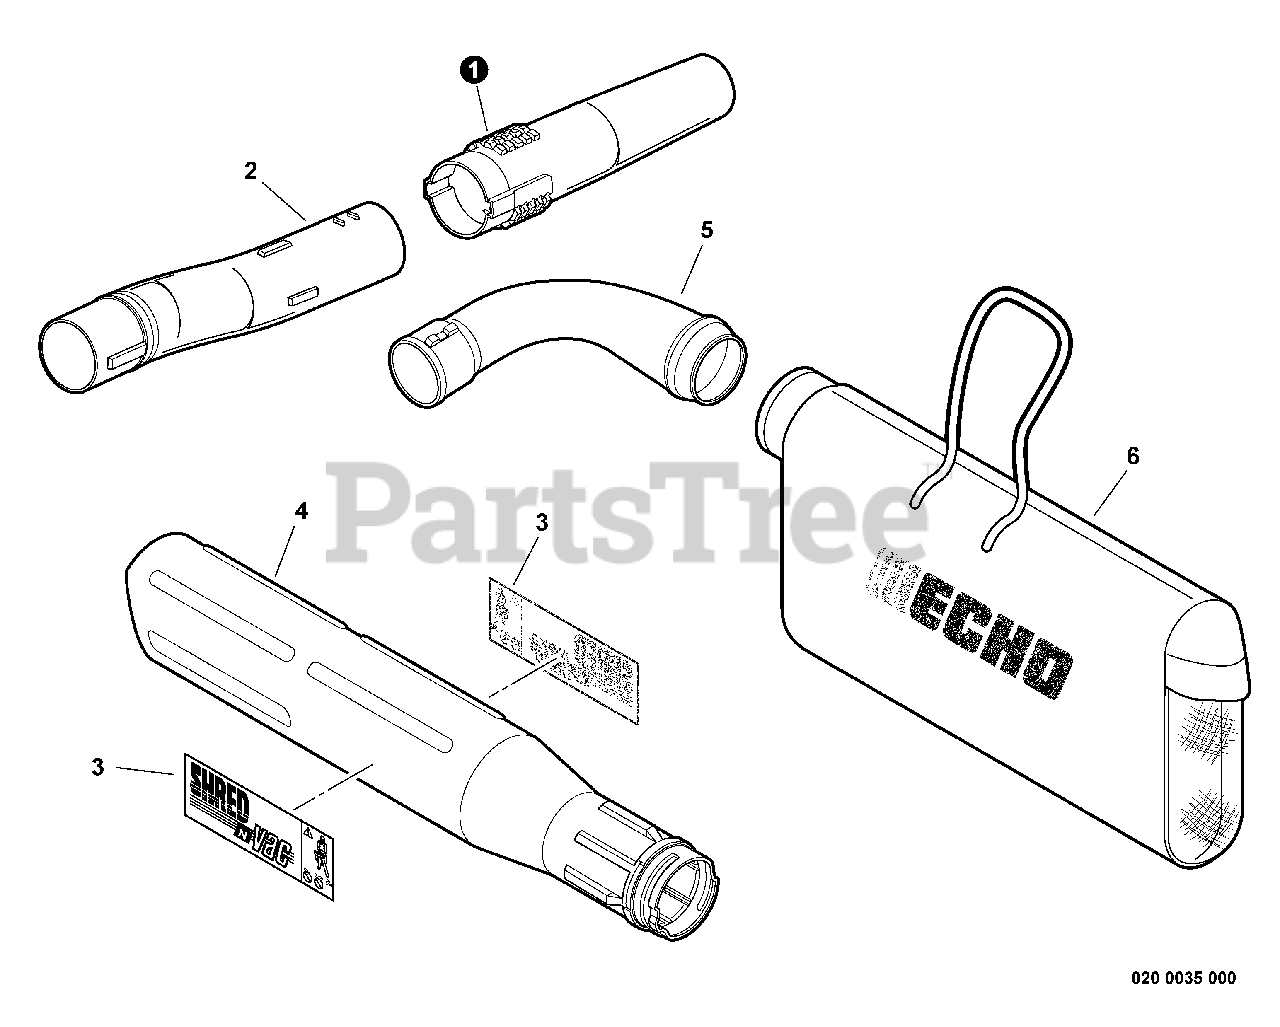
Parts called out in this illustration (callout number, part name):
1	TUBE, BLOWER - ROUND NOZZLE
2	TUBE, BLOWER - CURVED
3	LABEL, SHRED'N VAC
4	TUBE, BLOWER - SUCTION
5	TUBE, BLOWER - ELBOW
6	BAG, DEBRIS
